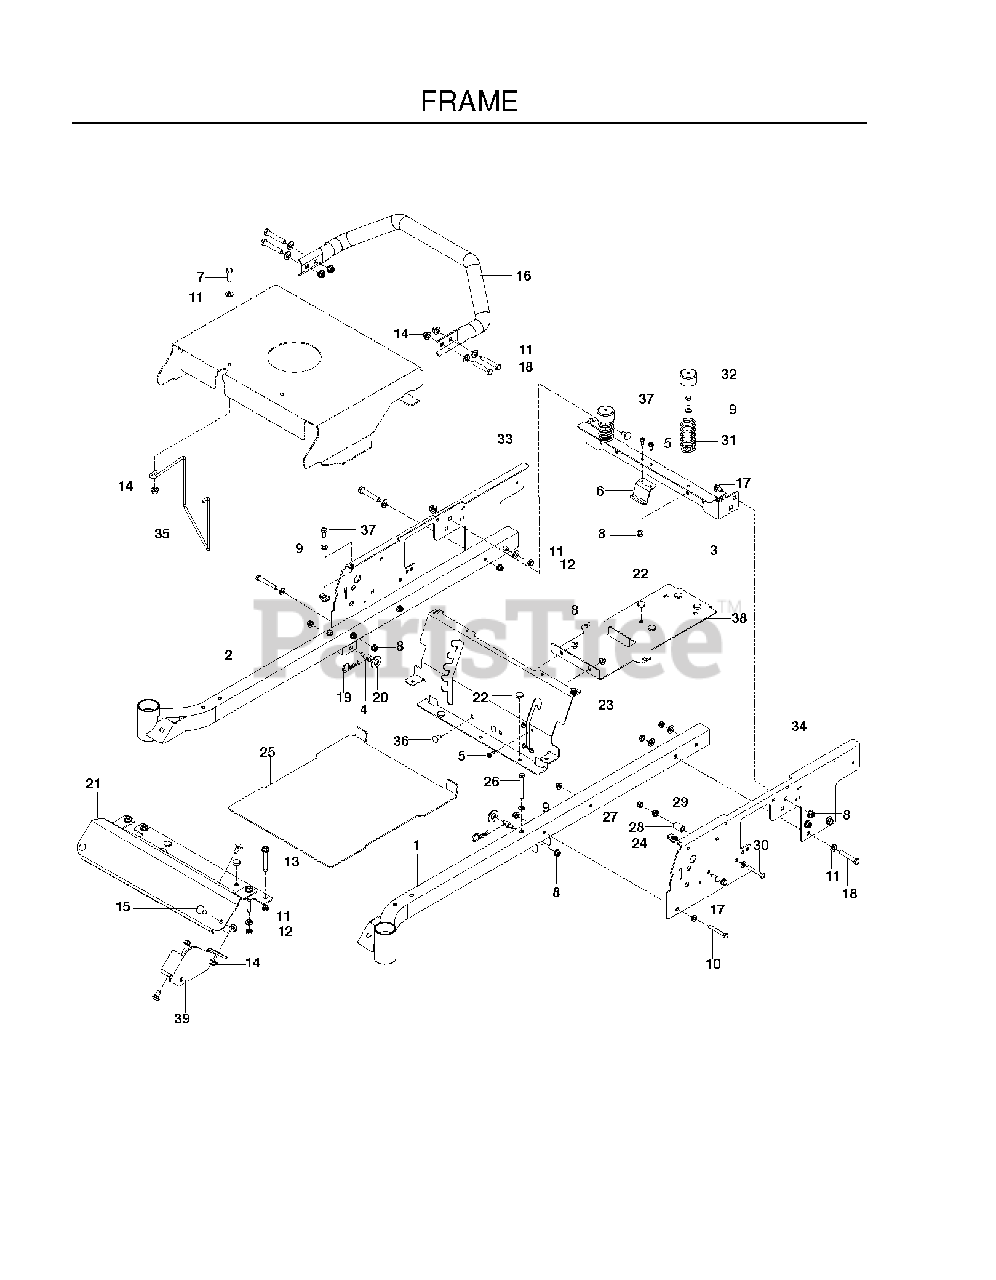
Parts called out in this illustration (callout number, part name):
1	FRAME, TUBE, LH, BLUE
2	FRAME TUBE, RH, BLUE
3	SEAT SUPPORT, REAR, BLUE
4	STUD.FASTNER.W/ANTI-ROTATE
5	SCREW 1/4 X 5/8
6	HOLDING DEVICE, FUEL TANK, BLK
7	HCS 3/8C X 1 1/4 GR5
8	5/16-18 NYLOC FLANGE NUT
9	FLAT WASHER 5/16 SAE
10	CAPSCREW
11	WASHER 3/8 SAE FLAT
12	NUT HEX 3/8-16 NYLON, THIN
13	ENGINE BOLT, SPECIAL
14	NUT 3/8-16 HEX FLG NYLOC ZD
15	RHSNB 3/8C X 1
16	IMPACT BAR, BLUE
17	RHSNB 3/8-16 X 3/4 GR5 ZD
18	HCS 3/8C X 2 1/4
19	HAIRPIN #4
20	WASHER 5/8 FLAT
21	FOOT REST, BLUE
22	GROMMET, BUMPER
23	PANEL.SEAT.SUPPORT.BLUE.DIXON
24	U-CLIP 5/16-18 NUT RETAINER
25	FOOT PLATE, BLUE
26	HCS 5/16C X 2-3/4
27	NUT 5/16C WHIZ
28	BUSHING
29	NUT 5/16 NYLOC
30	HCS 5/16-18X2
31	SEAT SPRING
32	SPRING CAP
33	PLATE.RH.SIDE.BLUE.DIXON
34	PLATE.LH.SIDE.BLUE.DIXON
35	KEEPER, BELT ENGINE
36	BOLT 5/16C X 3/4" CARRIAGE
37	HCS 5/16C X 3/4
38	SUPPORT, TANK/BATT, BLK
39	BRACKET, FRONT DECK, BLK
